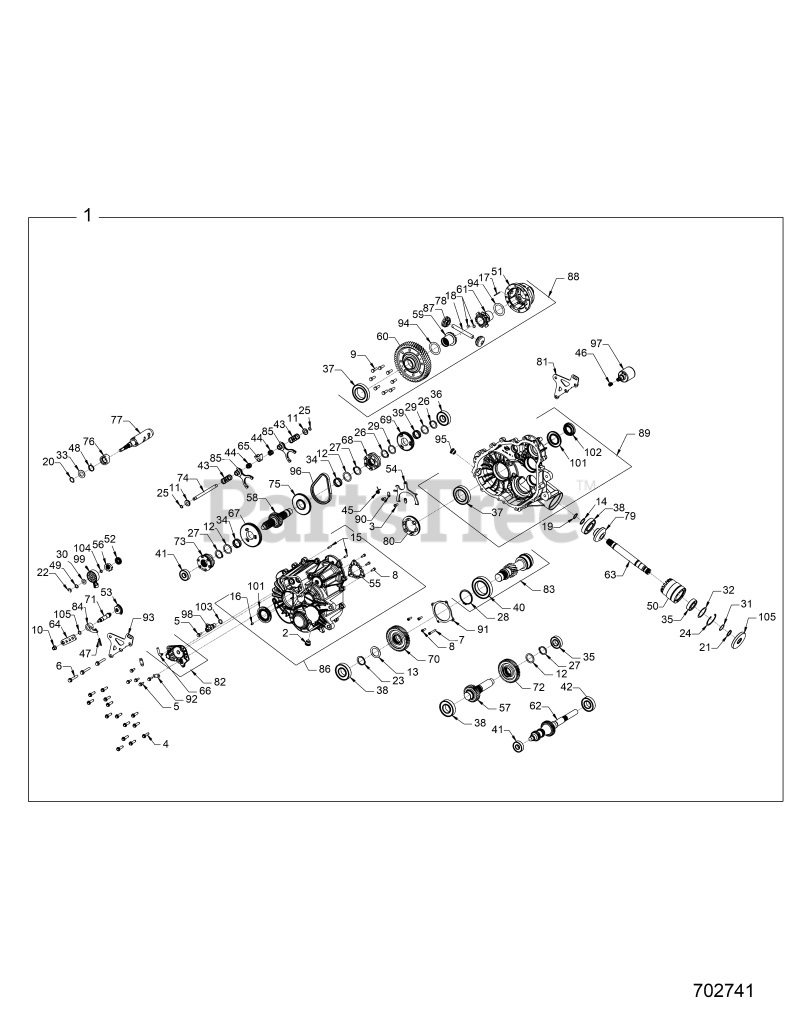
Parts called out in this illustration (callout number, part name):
1	ASM-GEARCASE,GAS
2	PLUG-SOCKET HEAD W/MAG,M18X1.5
3	SCREW, TORX PAN HD M6 X 1 X 16
4	SCREW-HEXFLANGEHEAD,M8X1.25X30
7	SCR-M6X1.0X40,SOC/CAP(105344)
8	SCR-SCKT HD,CP,M6X1X18(105355)
9	SCREW-CAP HH,M8 X 1.25 X 20
10	NUT-M8X1.25,HXFLG,NYLN(110093)
11	WASHER-CUP
14	WASHER, 22.5 X 30 X 1.5
15	PIN, DOWEL, 6 X 20
16	SPRING-SLOTTED PIN,6MM
17	PIN, DOWEL 3X40
18	PIN, DOWEL 8X10
19	RING, RETAINING
20	RING, RETAINING BASIC EXTERNAL
21	RING, SNAP
22	RING-RETAINING
23	RING,RETAINING
24	RING,RETAININGBASICINTRNL2.047
25	RING-RETAINING
26	RING,RETAINING
27	RING, RETAINING, EXTERNAL
28	RING, RETAINING
29	WASHER,THRUST
30	WASHER,THRUST,.446X.88X.025
31	SHIM 1.180 X .995
32	SHIM 2.040 OD X 1.630 ID
33	SPACER, 19.4 X 34 X 2
34	BEARING,NEEDLE
37	BEARING, BALL
38	BEARING-BALL
39	BEARING,NEEDLE
40	BEARING, BALL
41	BEARING, BALL
42	BEARING, BALL 6206RSH2 STD 30X62X16
43	SPRING-COMPRESSION
44	SPRING-COMPRESSION
45	SPRING, TORSION RETURN
46	SPRING,COMPRSSN.54ODX.44IDX.05
47	SPRING, COMPRESSION DETENT
48	SPRING, TORSION
49	WASHER-SPRING,210393
50	TUBE, SNORKLE MACH
51	CARRIER, DIFFERENTIAL MACH
52	GEAR-SECTOR,16T
53	GEAR-SECTOR,31T-CUT TO 11T
54	SHIFT FORK (270507)
55	PARK PLATE (270509)
56	STAR, DETENT
57	SHAFT, IDLER, 29T
58	SHAFT, REVERSE 27T
59	GEAR, OUTPUT 14T MACH
60	GEAR, 53T OUTPUT
61	GEAR, OUTPUT 14T DISCONNECT MACH
62	SHAFT, INPUT, HELICAL
63	SHAFT, FRONT OUTPUT
64	BELLCRANK, 42 DEG
65	COLLAR-SHIFT
66	TUBE-VENT,90-1/4" HOSE
67	GEAR-LOW,67T(352856)
68	DOG, ENGAGEMENT, 6-FACE
69	GEAR, 53T
70	GEAR, 46T, STAGE 3
71	SHAFT, SHIFT
72	GEAR, 46T STAGE 2
73	SHIFT DOG, PARK/LOW (353357)
74	RAIL-SHIFT SHAFT(353622)
75	SPROCKET, 48T, 6-FACE
76	PARK CAM
77	DRUM, SHIFT MACH
78	PIN, DIFFERENTIAL
79	GEAR, 13T SNORKEL
80	DOG, ENGAGEMENT
81	WELDMENT, REAR MOUNT BRACKET
82	SUBASSY COVER, SECTOR GEARS
83	ASM-SUB,PINION SHAFT(411759)
84	ROLLER PAWL
85	SUBASSEMBLY, SHIFT FORK
86	SUBASSEMBLY RH COVER
87	SUBASSEMBLY, PINION GEAR
88	SUBASSEMBLY, DIFFERENTIAL
89	SUBASSEMBLY, LH CASE
90	RETAINER-FORK
91	COVER, BEARING, CENTER DRIVE
92	BRKT-MOUNT(430592)
93	BRACKET, REAR MOUNT
94	WASHER THRUST 40.83 X 56.25 X 0.38
95	PLUG-SKT HD 1SO 6149,M18 X 1.5
96	CHAIN, SILENT
97	SOLENOID
98	SENSOR-SPEED,TRANS
99	SWITCH, ROTARY 2 PIN RESISTIVE
100	SEAL-TRIPLE LIP 25X80X10
101	SEAL-TRIPLE LIP,VITON,40X70X7
102	SEAL, TRIPLE LIP, VITON HELIX 30X47
103	O-RING, -113
